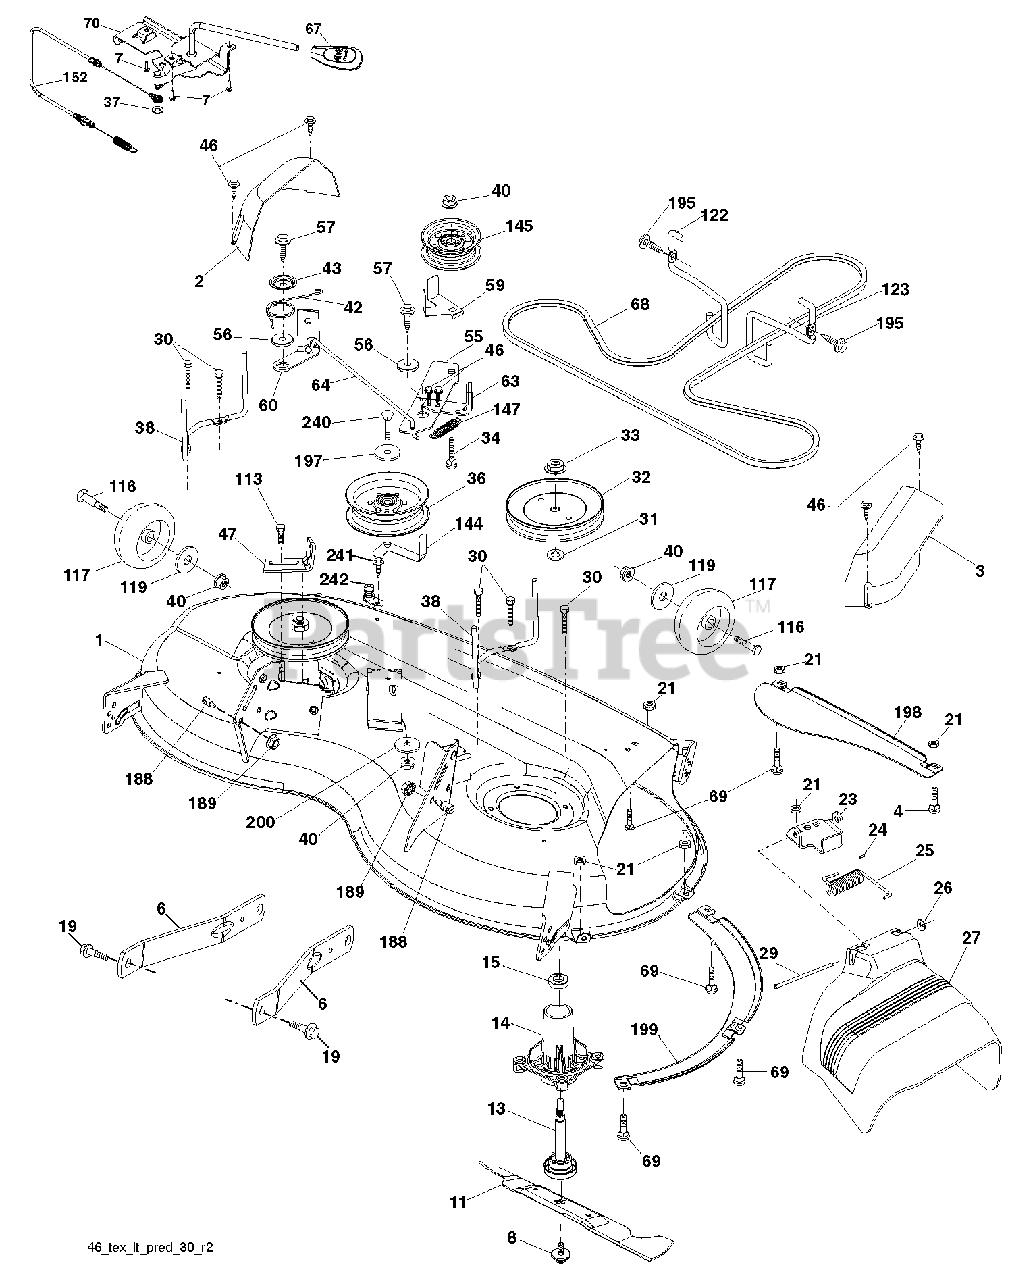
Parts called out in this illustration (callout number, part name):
2	COVER.MANDREL.LH.46"
3	COVER.MANDREL.RH.46"
4	BOLT
6	ARM.SUSPENSION.MOWER.R
7	SCREW.#10 X 0.750.BOS (2 2)
8	BOLT.WASHER.ASM.7/16-2
11	BLADE.MOWER.46".HI.LIFT
13	SHAFT.ASM.MDRL.N/GREASE.38
14	HOUSING.MANDREL.4PT.
19	BOLT.SHOULDER
21	LOCKNUT
23	BRKT.DEFLECTOR.38"2005+
24	CAP-SLEEVE LT
25	SPRING.TORSION.DEFLECT
26	NUT PUSH M
27	SHIELD.DEFLECTOR.MOWER.46"BLAC
29	ROD.HINGE
30	SCREW, WASHER HEAD
31	WASHER.SPACER.MANDREL
32	PULLEY.MANDREL.5.438.PD
33	NUT.FLANGE.LOCK.TOP
34	BOLT.3/8-16X1.50
36	PULLEY.IDLER.2006
38	KEEPER.BELT.MANDREL.PULLEY
40	NUT LOCK FLG 3/8-16 UNC
42	SPRING.TORSION.BRAKE
43	SRPING.TORSION.RETAINE
46	SCREW.1/4-20X5/8
47	BRKT.CLUTCH.CABLE
55	IDLER.ARM
56	SPACER.RETAINER
57	SCREW 3/8-16X1
59	GUARD, BELT
60	ARM BRAKE MOWER RH 38"
64	LINKAGE BRAKE
67	HANDLE.CLUTCH.CABLE.LT
68	V-BELT
69	BOLT
70	CLUTCH.ASM.MANUAL.YT.PREDATORQ
113	BOLT.5/16HEX.WHS.HD
116	BOLT M
117	WHEEL.GAGE.HALF.SPOKED
119	WASHER
122	KEEPER BELT ENGINE LH
123	KEEPER BELT RH
144	KEEPER.BELT.MOWER
145	PULLEY.IDLER.48"PRIMARY
147	SPRING RETURN
152	CABLE.MECHANICAL.CLUTCH
188	STUD.FASTNER.W/ANTI-ROTATE
189	NUT LOCK HEX FLANGE 5/16-18
195	SCREW, 3/8-16X3/4
197	WASHER
198	BAFFLE CENTER FRONT
199	BAFFLE FRONT RH
200	WASHER.13/32 X 1 X 1/2.11GUARD
240	BOLT-HEX EAK
241	SCREW.TT.#10-32X.5.3/8.FLANGE
242	PORT.WASHOUT
